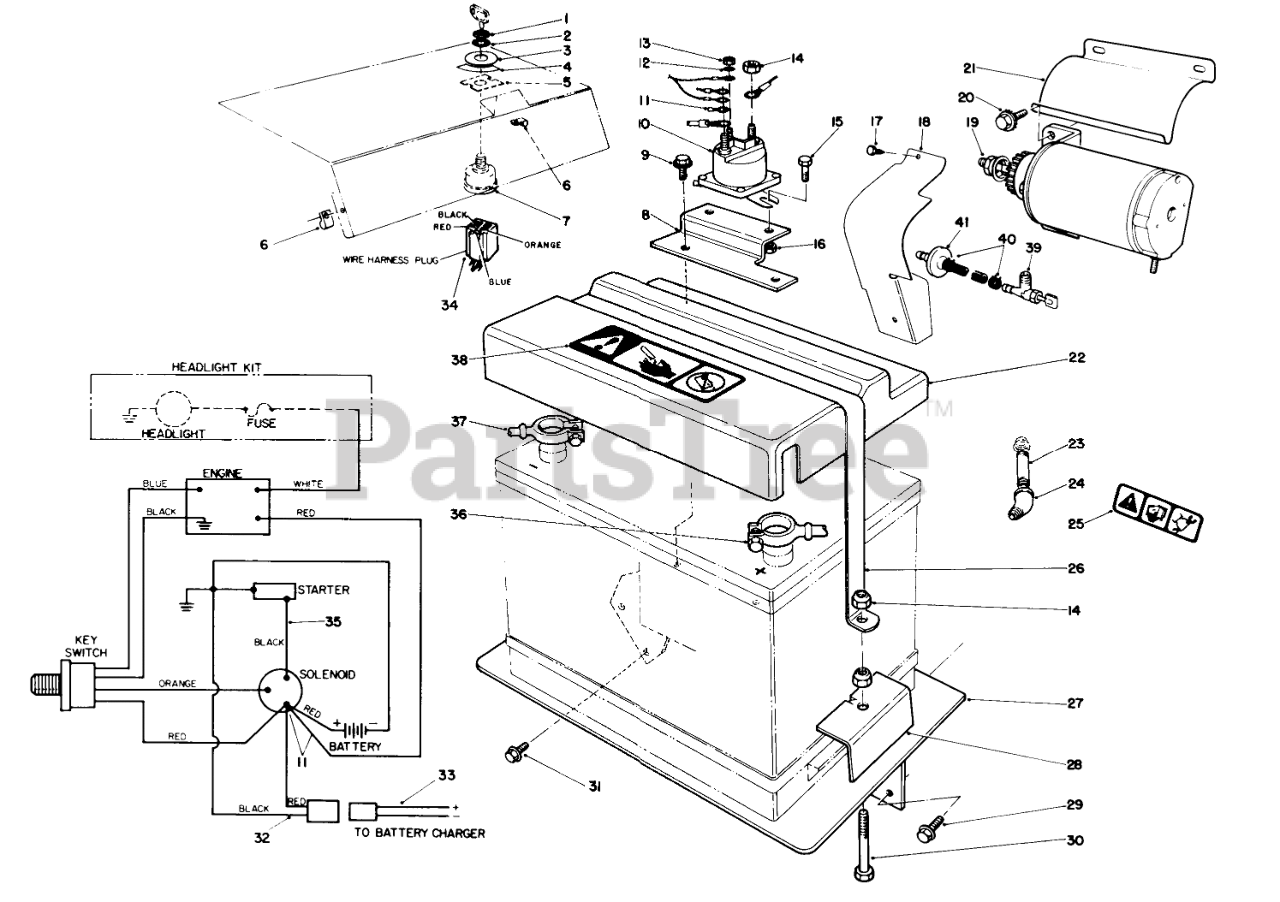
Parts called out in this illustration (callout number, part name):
1	NUT-HH
2	WASHER-TOOTH, INTERNAL
3	WASHER
4	DECAL
5	ADAPTER
6	R CLAMP
7	Switch-Starter (Incl. Ref. #1-2)
8	BRACKET
9	SCREW-HWH
10	SOLENOID
11	RING TONGUE TERMINAL
12	WASHER-LOCK, INT
13	NUT-HEX
14	NUT-LOCK, NI
15	SCREW-HH
16	NUT-LOCK, NI
17	Screw
18	Shield-Pinion
19	Starter Motor Ass-y
20	Crew
21	Shield-Dip
22	BATTERY COVER
23	NIPPLE 3/8NPTX 1.50
24	ELBOW
25	DECAL-WARNING
26	Strap Battery
27	Plate-Battery
28	BATTERY CLAMP
29	SCREW-HHF
30	SCREW-HH
31	SCREW-HHF
32	MALE WIRE ASM
33	FEMALE WIRE ASM
34	WIRE HARNESS
35	STRT MTR-SOLNOID WIRE
36	BATT-SOLENOID CABLE
37	KEY-SHIFT
38	DECAL
39	Valve-Fuel Tank
41	Filter
